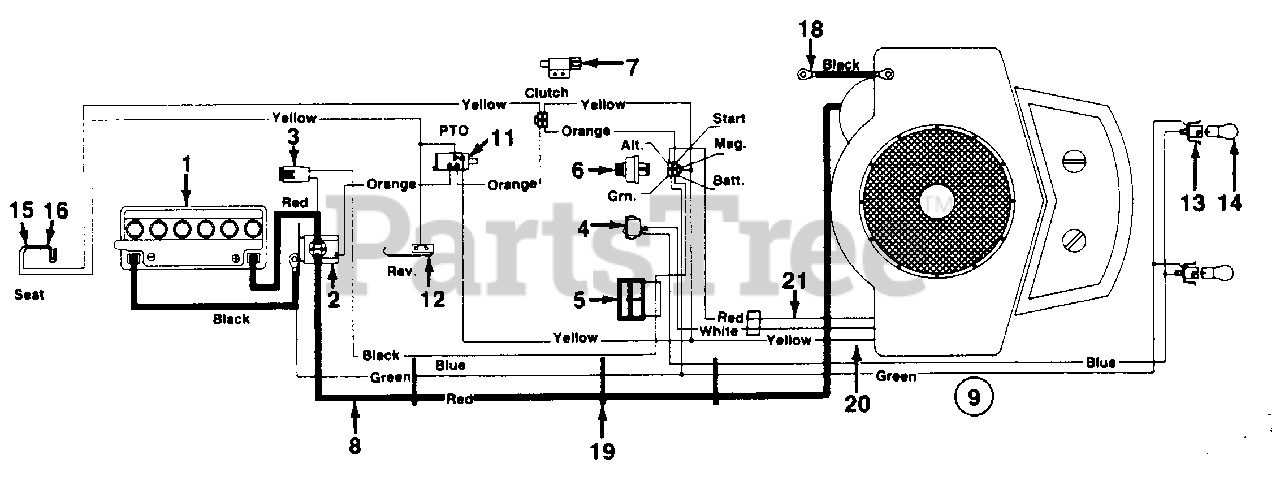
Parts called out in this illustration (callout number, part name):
1	Battery
2	Solenoid
3	Fuse 7.5 Amp.
4	Light Switch
5	Ammeter
6	Ignition Switch
7	Safety Switch
8	ElectricWire 32.5" Lg.
9	Wire Harness
11	Safety Switch
12	Satety Switch
13	Socket
14	Bulb
15	Safety Switch
16	Safety Switch
18	Ground Wire - 7.5" Lg.
19	Cable Tie
20	Magneto Adapter
21	Alternator Ext.
